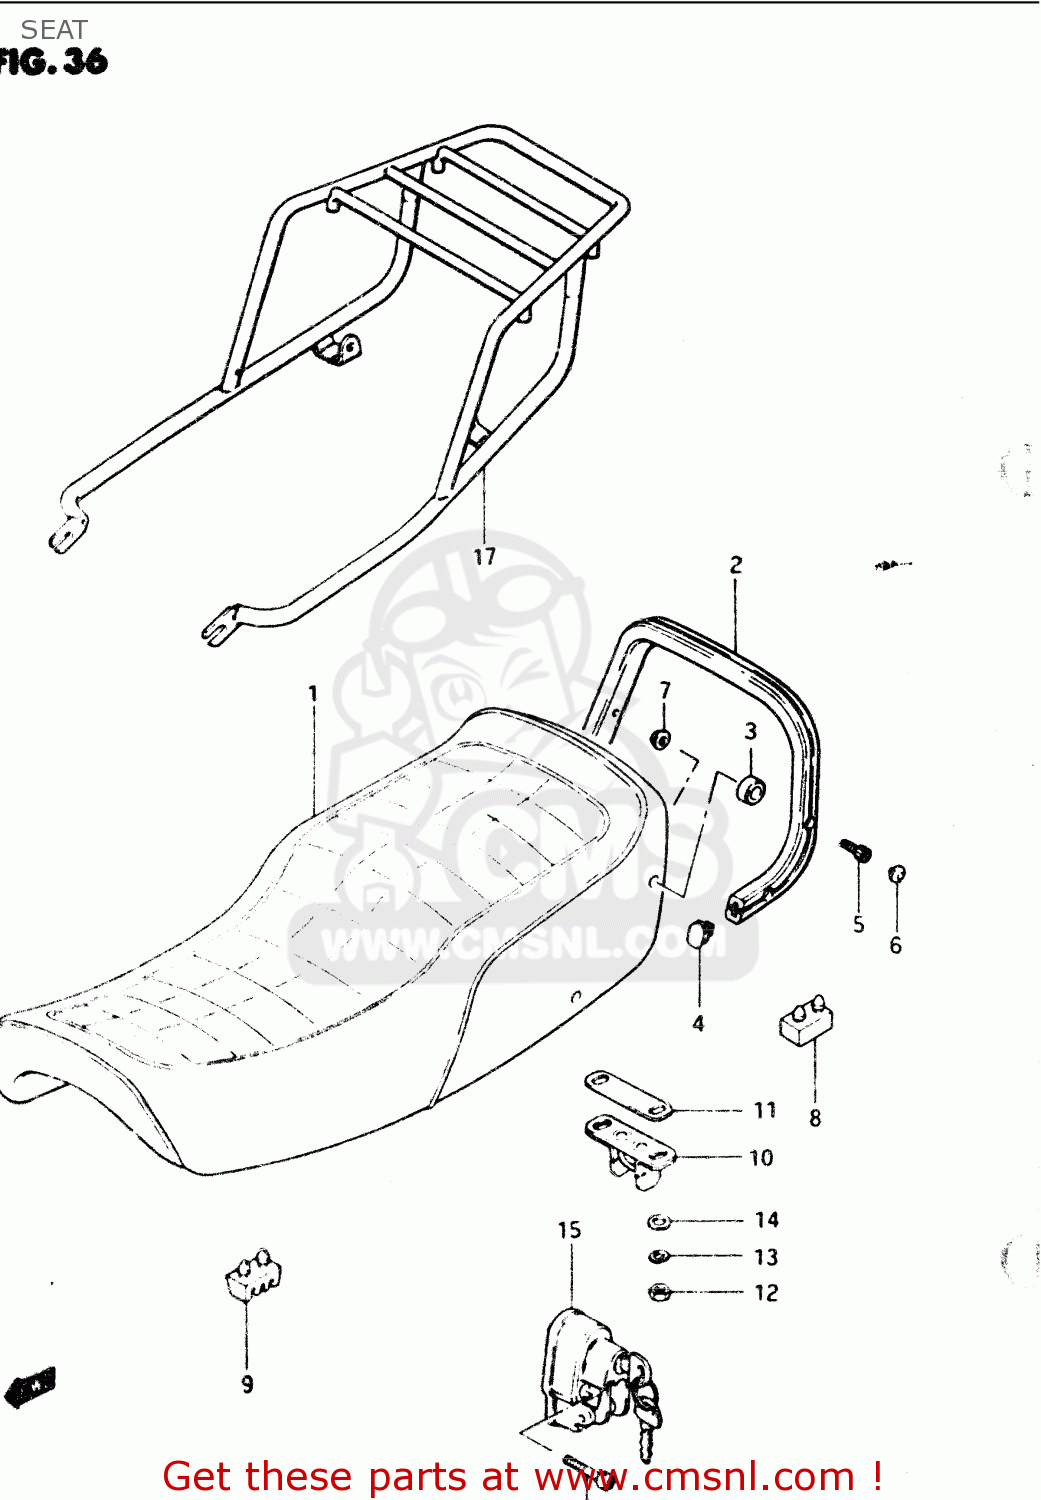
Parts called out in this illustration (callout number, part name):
1	SEAT (BLACK)
2	HANDLE,PILLION RIDER
3	SPACER,REAR
4	END,PILLION RIDER HAND
5	BOLT, REAR (8X30)
6	CAP(OD:14.5)
7	NUT
8	CUSHION(40X23X12.7)
9	CUSHION,SUPPORT(50X25X32)
10	STRIKER,SEAT LOCK
11	SHIM,SEAT LOCK STRIKER
12	NUT
13	WASHER,LOCK
14	WASHER
15	LOCK ASSY,HELMET
16	BOLT
17	CARRIER, SPORTS
